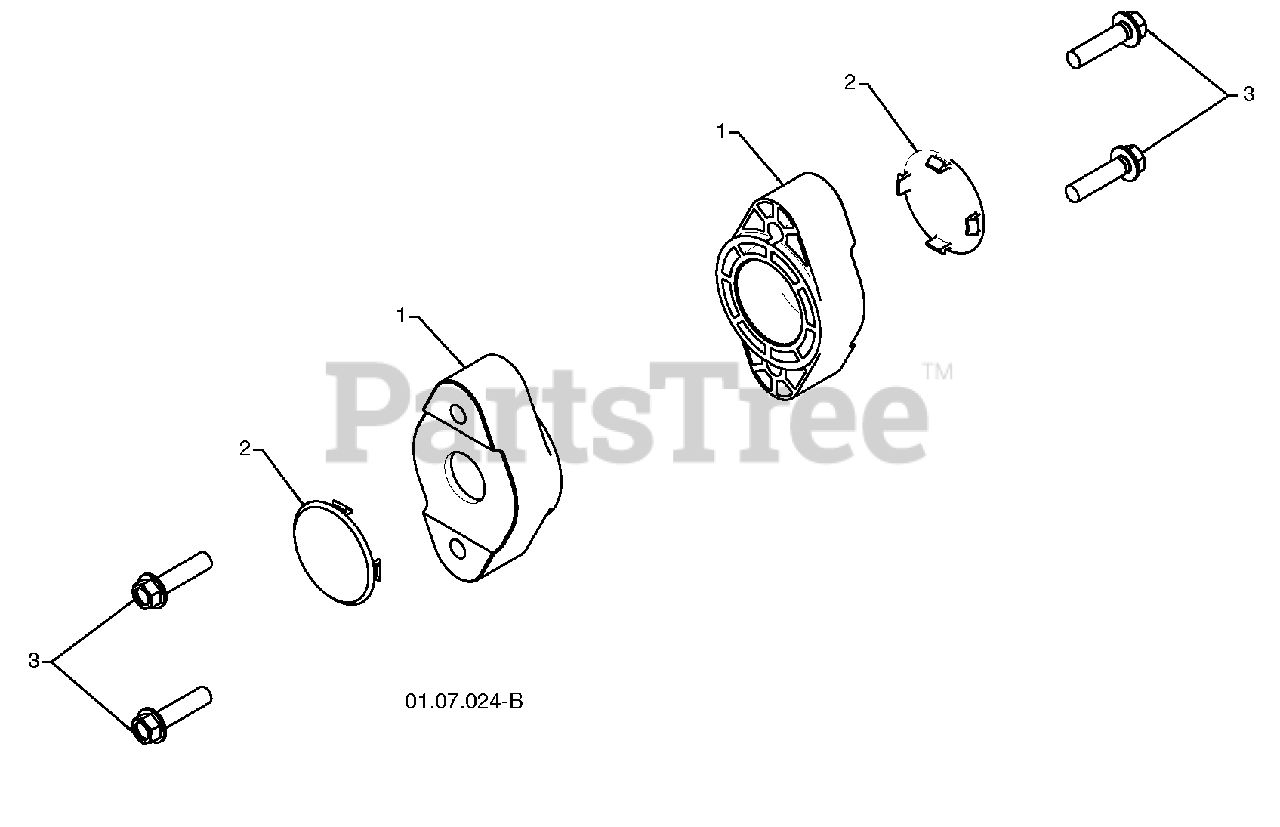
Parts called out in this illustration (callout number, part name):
1	Auger Bearing
2	Bearing Plug
3	Screw 5/16-18 X 1.00
